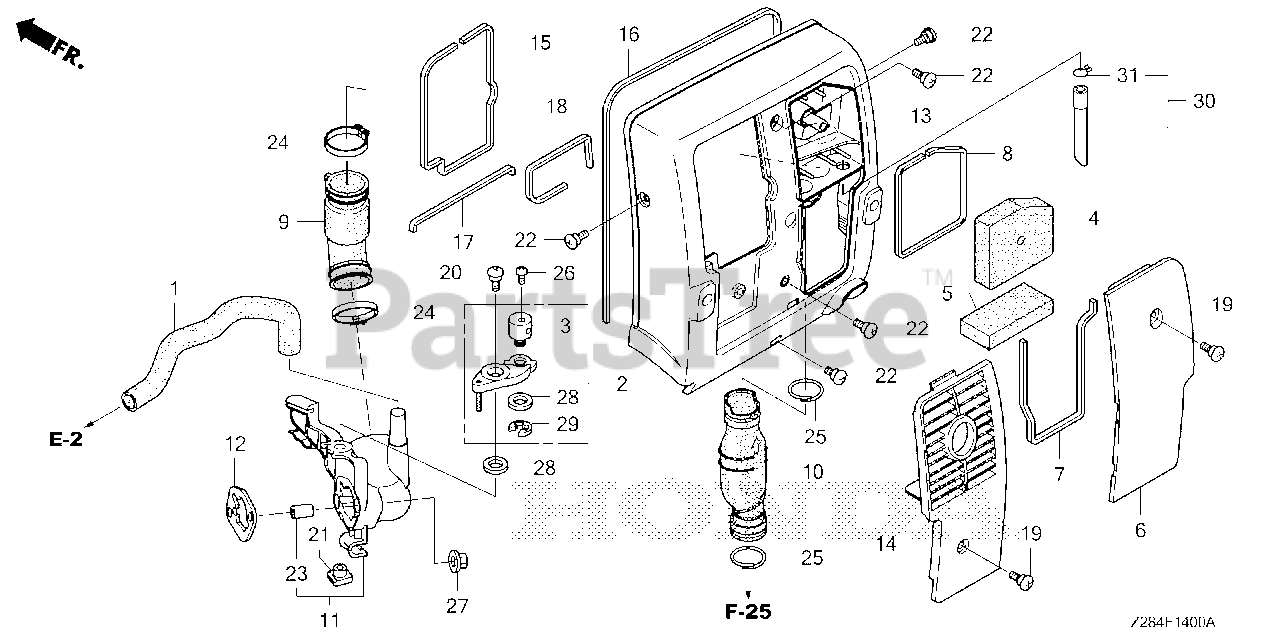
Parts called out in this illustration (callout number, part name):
1	TUBE, BREATHER
2	LEVER ASSY., CHOKE
3	HOLDER, CABLE
4	ELEMENT, AIR CLEANER
5	FILTER (OUTER)
6	COVER, AIR CLEANER *NH314* (CONDUCT GRAY)
7	SEAL A, AIR CLEANER COVER
8	SEAL C, AIR CLEANER COVER
9	TUBE, AIR CLEANER CONNECTING
10	TUBE, RESONATOR
11	JOINT, AIR IN.
12	GASKET, AIR IN. JOINT
13	COVER, RR. *NH314* (CONDUCT GRAY)
14	COVER, MUFFLER PROTECTOR *NH314* (CONDUCT GRAY)
15	SEAL, RR. COVER (565MM)
16	SEAL, RR. COVER (UPPER)
17	SEAL, RR. COVER (LOWER)
18	SEAL, RR. COVER (261MM)
19	SCREW, SPECIAL (6X16)
20	SCREW, SPECIAL (6X12)
21	NUT, SPECIAL (6MM)
22	SCREW, SPECIAL (6X15)
23	COLLAR, IN. JOINT
24	CLAMP, HOSE
25	CLIP, AIR CLEANER TUBE
26	SCREW, PAN (4X6)
27	NUT, FLANGE (6MM)
28	WASHER, PLAIN (6MM)
29	E-RING (5MM)
30	TUBE ASSY., AIR CLEANER
31	CLIP, BREATHER TUBE
